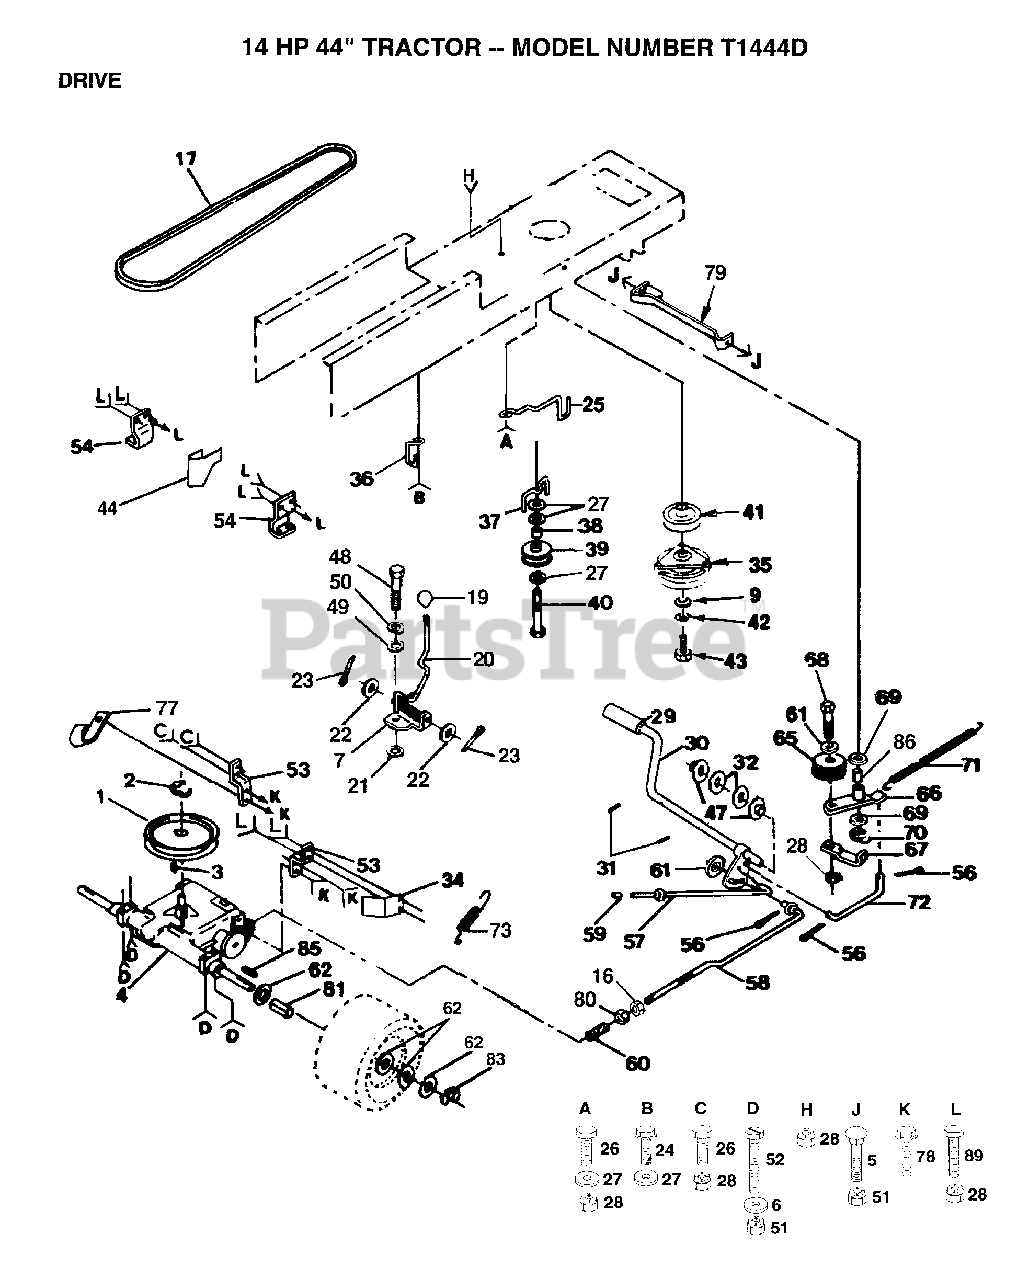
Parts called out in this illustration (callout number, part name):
1	"PULLEY,TRANSAXLE"
5	BOLT
6	WASHER T
7	PLATE SHIFT LT
9	WASHER
16	NUT
18	SCREW
19	CONTROL KNOB LT
20	ROD SHIFTER
21	WASH-SHFT PLT LT
22	WASHER
23	PIN COTTER 1/8
24	SCREW
25	KEEPER.BELT.ENG.L
26	BOLT
27	WASHER
29	PEDAL COVER T
32	WASHER LT
34	"KEEPER,BELT RH"
37	BELT KEEPER LT
38	SPACER T
39	PULLEY.IDLER.FLAT
40	BOLT
41	PULLEY ENGINE
42	LOCKWASHER
44	"KEEPER,BELT LH"
47	NYLON BEARING
49	WASHER LT
50	LOCKWASHER
52	BOLT
53	STRAP TORQUE
54	BRACKET LT
56	COTTER PIN
57	PARKING BRAKE ROD
60	"SPRING,ROD BRAKE"
61	WASHER
62	WASHER
66	ARM IDLER
67	RETAIN BELT
69	WASHER LT
70	KLIP RING
71	"SPRING, RETURN LT"
72	"LINK, CLUTCH T"
78	SCREW
79	BRACKET.ASM.MTG
80	NUT
81	SPACER LT
83	E-RING LT
85	SQUARE KEY
86	"LY, BEARING"
